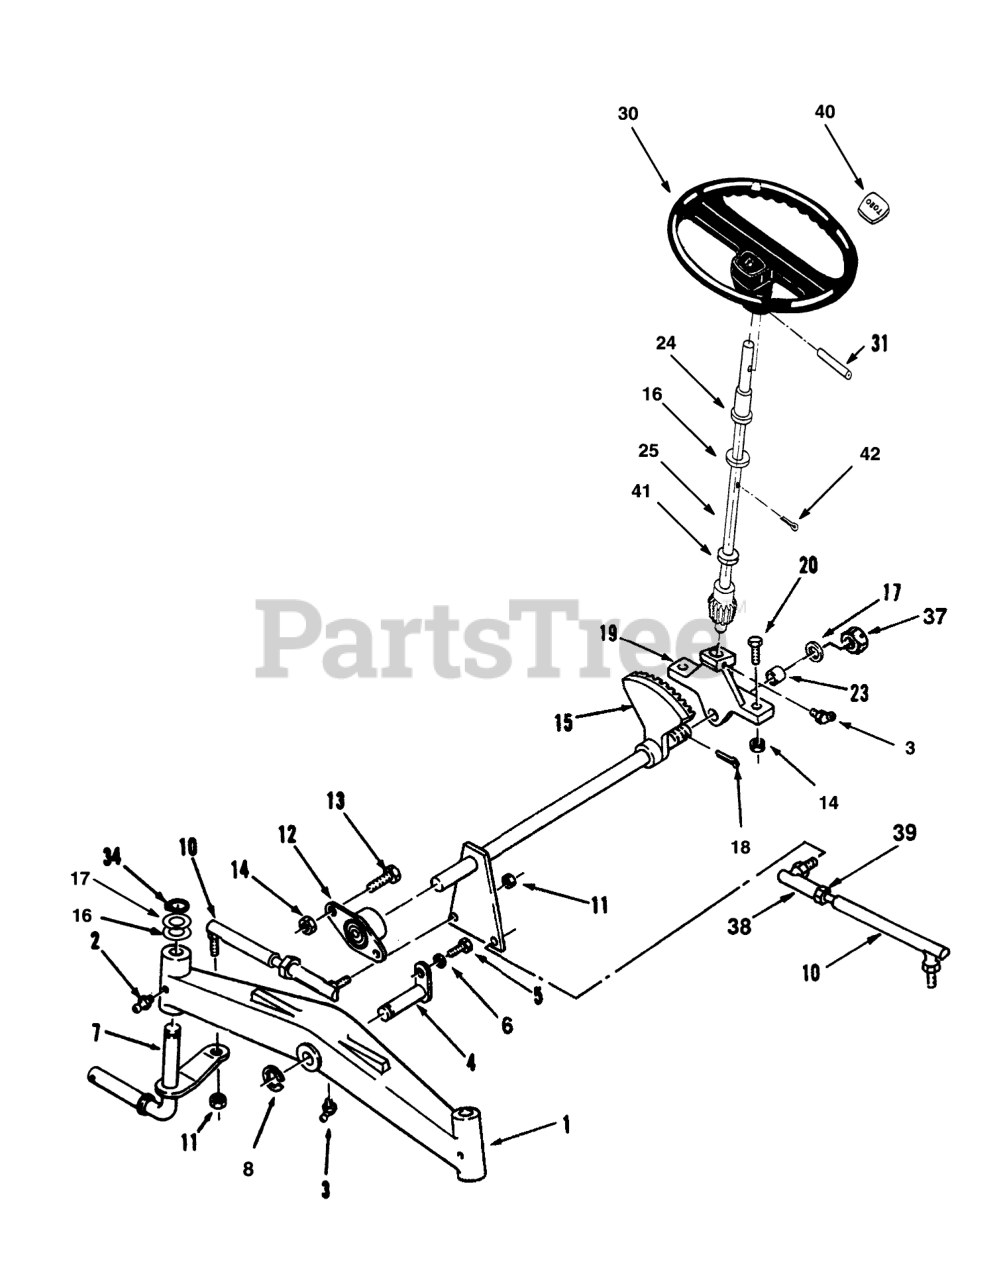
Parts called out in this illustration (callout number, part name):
1	AXLE-FRONT
2	FITTING-GREASE
3	FITTING-GREASE
4	PIN AND PLATE ASM
5	SCREW-HH
6	WASHER-LOCK
7	LH SPINDLE ASM
8	E-RING
10	Tie Rod Assembly (Includes Item 38 & 39)
11	NUT HEX 3/8-24 E.S.
12	BEARING-FLANGED
13	SCREW-HH
14	NUT-LOCK, NI
15	Shaft
16	WASHER-SHIM
17	WASHER
18	PIN-COTTER
19	Support-Steering
20	SCREW-HH
23	BEARING-BRONZE
24	BEARING-FLANGED
25	STEERING SHAFT WA
30	Steering Wheel (Incl. Ref. #40)
31	PIN-ROLL
34	RING-RETAINING
37	NUT-HEX, SLOTTED
38	BALL-JOINT
39	NUT-6
40	STRG-WHL INSERT TORO
41	O-RING
42	PIN-COTTER
